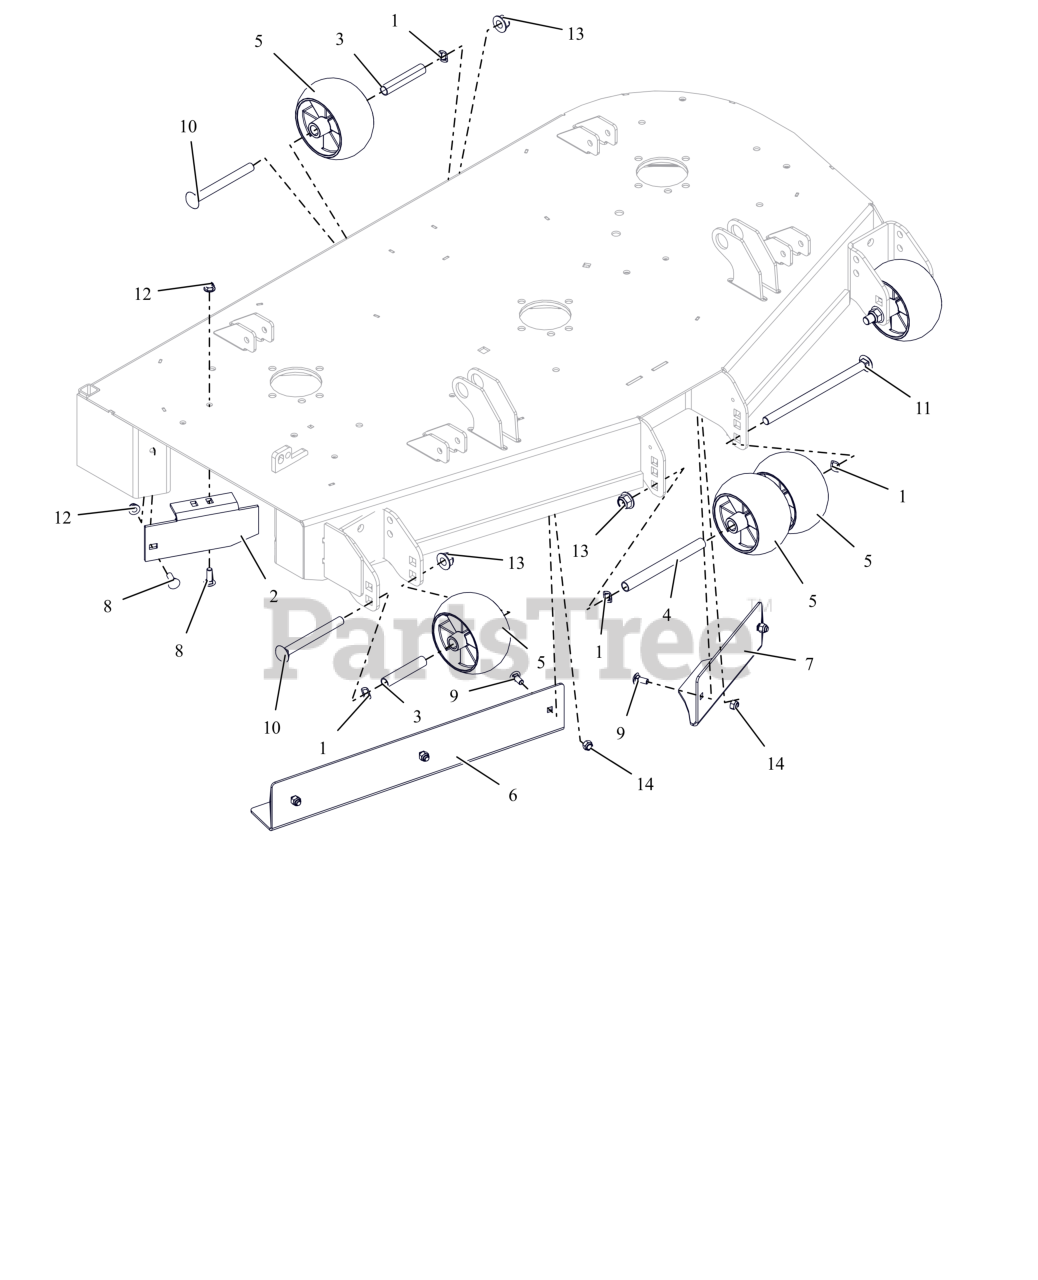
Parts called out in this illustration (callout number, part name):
1	WAVE WASHER .531X.781X.125FH
2	BAFFLE, 44/48" SIDE DISCHARGE
3	SPACER, .510X.625X3.35
4	SPACER, .510X.625X6.50
5	ANTI-SCALP WHEEL - 5X3 CTR
6	BAFFLE, 48" RH VACUUM (ORANGE)
7	BAFFLE, 44/48" LH VACUUM (ORANGE)
8	BLT,RHSN .31-18X1.00 G5 ZCC
9	BLT,RHSN .31-18X.75 G5 ZCC
10	BLT, RHSN .50-13X5.00 G5 ZCC
11	BLT, RHSN .50-13X8.50 G5 ZCC
12	NUT,LK-NYL-FLG .31-18 G5ZC120
13	NUT,NYL-FLG .50-13 GF ZCC
14	NUT,NYL .31-18 G5 ZCC
